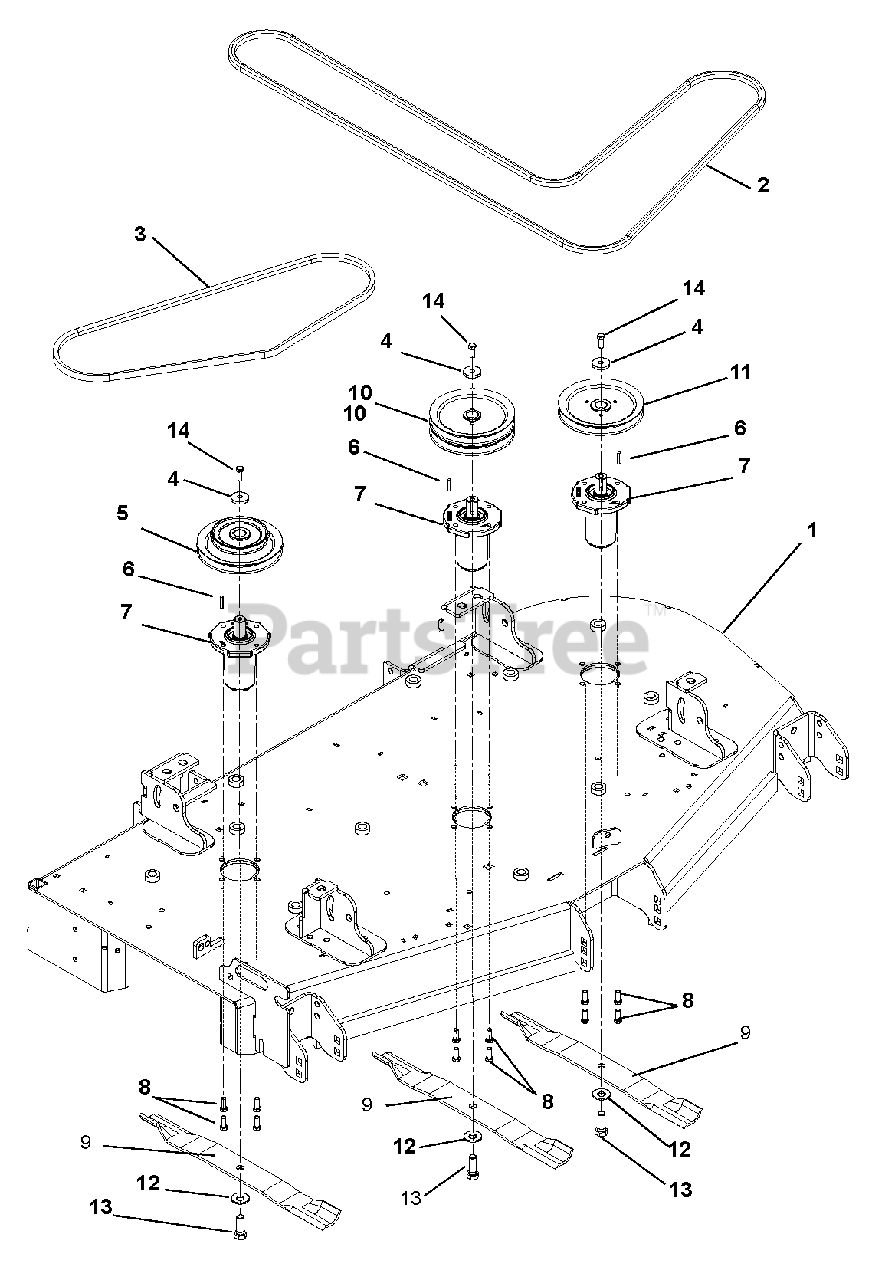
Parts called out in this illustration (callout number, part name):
1	Deck, 52"
2	Hex Belt, BB – Wrapped
3	V-Belt, B-Cogged
4	Retainer, Sheave
5	Sheave, 1" ID x 6.00" OD and 3.50" OD
6	Key, Square .25 x .25 x 1.00
7	Assembly, Spindle G3500
8	Bolt, Hex .38-16 x 1.00
9	Blade, Mulch 18.00"
10	Pulley, Double
11	Pulley, Single 1"ID x 6.00" OD
12	Washer, Bellville .63 x 1.625 x .14
13	Bolt, Hex .62-18 x 1.75 Grade 8
14	Bolt, Hex .38-16 x 2.75 Grade 8
